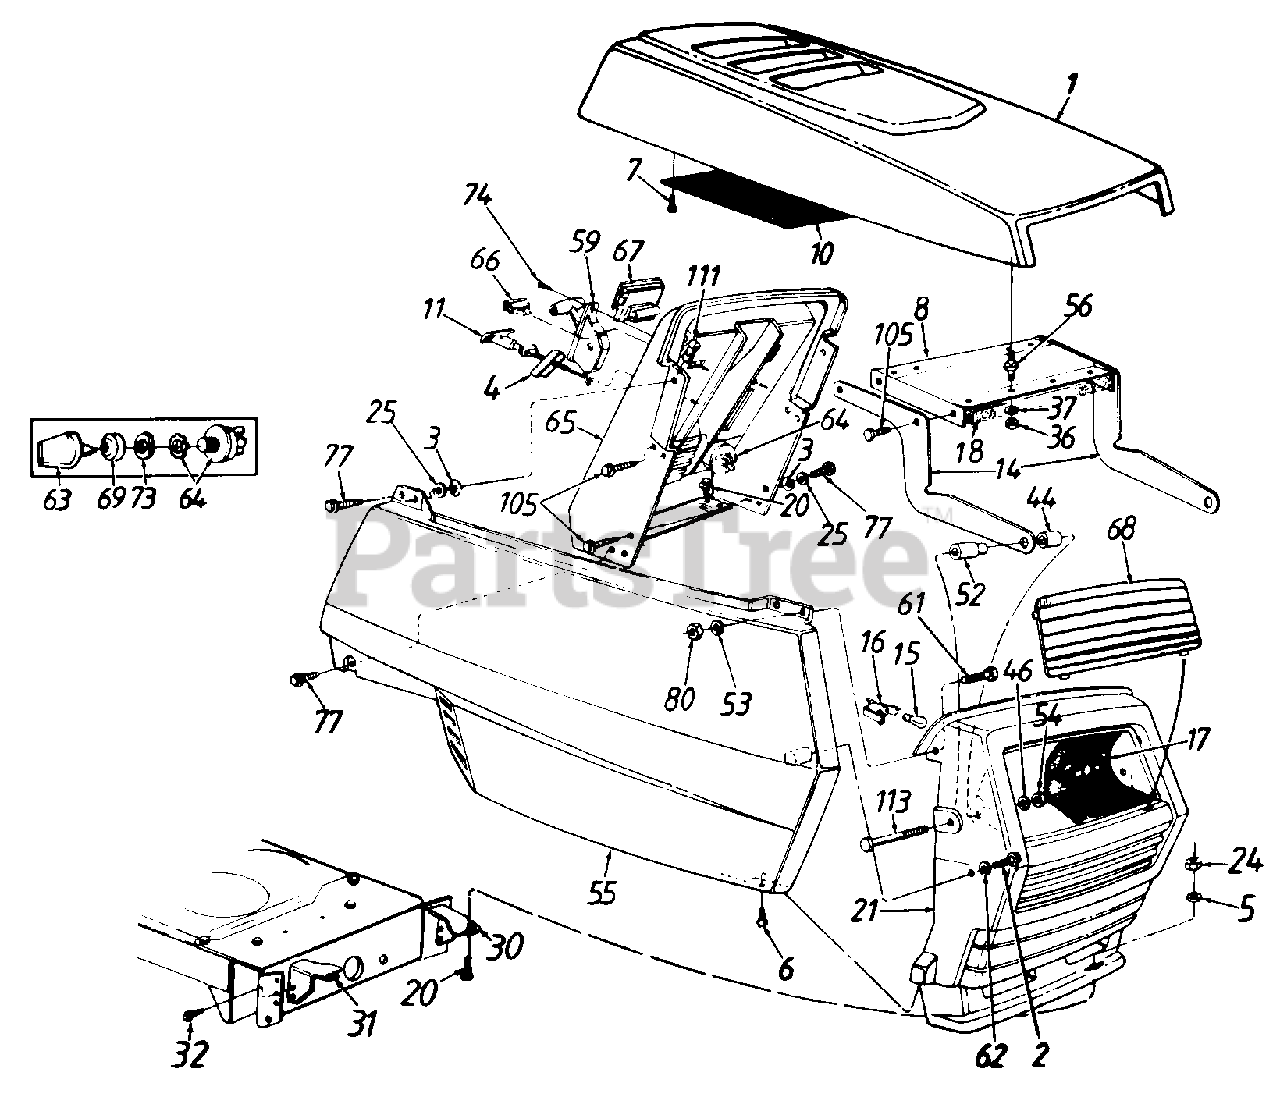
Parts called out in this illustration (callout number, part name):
3	Bolt Retainer 1/4" I.D.
4	Retainer Clip
5	Fl-Wash. .34" I.D. x .68"
6	Truss Mach. AB-Tap Scr. #10 x .5" Lg.
7	Hex Wash Hd. AB-Tap Scr. #8 x 5n Lg.
8	Hood Plate
11	Choke Control 38" Lg.
14	Hood Hinge
15	Lamp
16	Twist Lock-Lamp Socket
17	Reflector-Headlight
20	Hex Bolt 5/16-18 x .75" Lg.
21	Grille
24	Hex Nut 5/16-18 Thd.
25	Fl-Wash. 1/4" I.D. x .93" O.D.
30	Grille Mount Brk't.-L.H.
31	Grille Mount Brk't.-R.H.
32	Hex Wash. Hd. AB-Tap Scr. 5/16 x .75" Lg.
36	Hex Nut 1/4-20 Thd.
37	Bell-Wash. .265" I.D. x .75"
44	Spacer .33" I.D. x .625" O.D.
46	Fl-Wash. .328" I.D. x .68" O.D.
52	Shld. Spacer .33" l.D.
53	Fl-Wash. .281" I.D. x .5" O.D.
54	Hex L-Nut 5/16-18 Thd.
55	Side Cover-R.H.
56	Double Ended Stud 1/4-20 Thd.
59	Throttle Control Box Ass'y.
61	Hex Bolt 1/4-20 x .62" Lg.
62	Fl-Wash. .281" I.D. x .73" O.D.
64	Ignition Switch
65	Dash Panel
66	Light Switch
67	Ammeter
68	Lens
69	Ignition Switch Cap
73	Ignition Switch Nut
74	Truss Mach. AB-Tap Scr. #10 x .5" Lg.
77	Hex Wash. Hd. Tap Scr. 1/4 x.75" Lg.
80	Hex L-Nut 1/4-20 Thd.
105	Hex Tap Scr. 1/4-20 x .5" Lg.
111	Speed Nut 1/4-20 Thd.
113	Hex Bolt 5/16-18 x 2.75n
